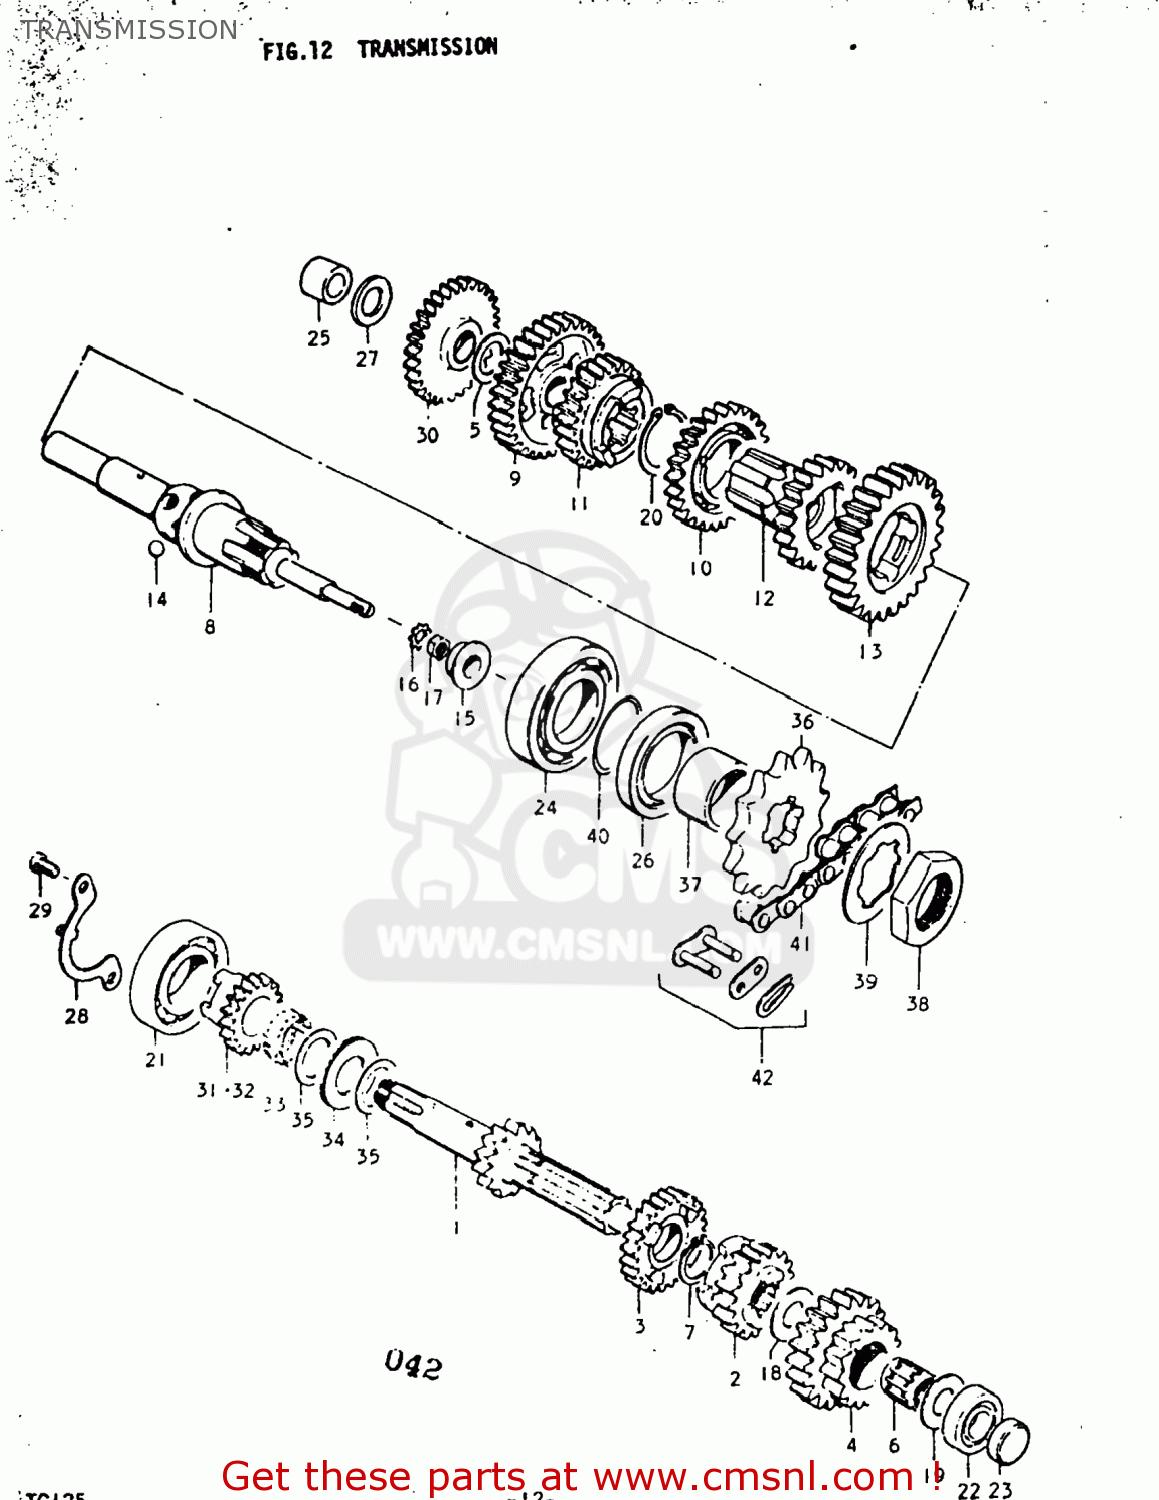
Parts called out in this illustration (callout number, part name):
1	SHAFT,COUNTER
2	GEAR,SECOND DRIVE
3	GEAR,THIRD DRIVE
4	GEAR,FOURTH DRIVE
5	WASHER,THRUST
6	ROLLER BEARING (15X19X1
7	CIRCLIP
8	SHAFT,DRIVE
9	GEAR,FIRST DRIVEN
10	GEAR,SECOND DRIVEN
11	GEAR,THIRD DRIVEN
12	GEAR,FOURTH DRIVEN
14	BALL
15	OIL SEAL
16	LOCK WASHER
17	NUT
18	WASHER,THRUST
19	WASHER
20	CIRCLIP
21	BEARING, RH
22	BEARING
23	PLUG
24	BEARING
25	BUSH
26	SEAL,OIL(30X44X6)
27	WASHER
28	RETAINER,CNTR SHAFT BEARING
29	SCREW
30	GEAR,KICK STARTER IDLE
31	GEAR,KICK STARTER DRIVE
32	GEAR,KICK STARTER DRIVE
33	BEARING(19.2X23.2X19)
34	BEARING(21X32X2.85)
35	WASHER(21X30X0.8)
36	SPROCKET,ENGINE
37	SPACER (25X30X12.4)
38	NUT
39	WASHER,LOCK
40	O RING(D:1,ID:24.5)
41	CHAIN ASSEMBLY,DRIVE
42	JOINT ASSEMBLY,CHAIN
